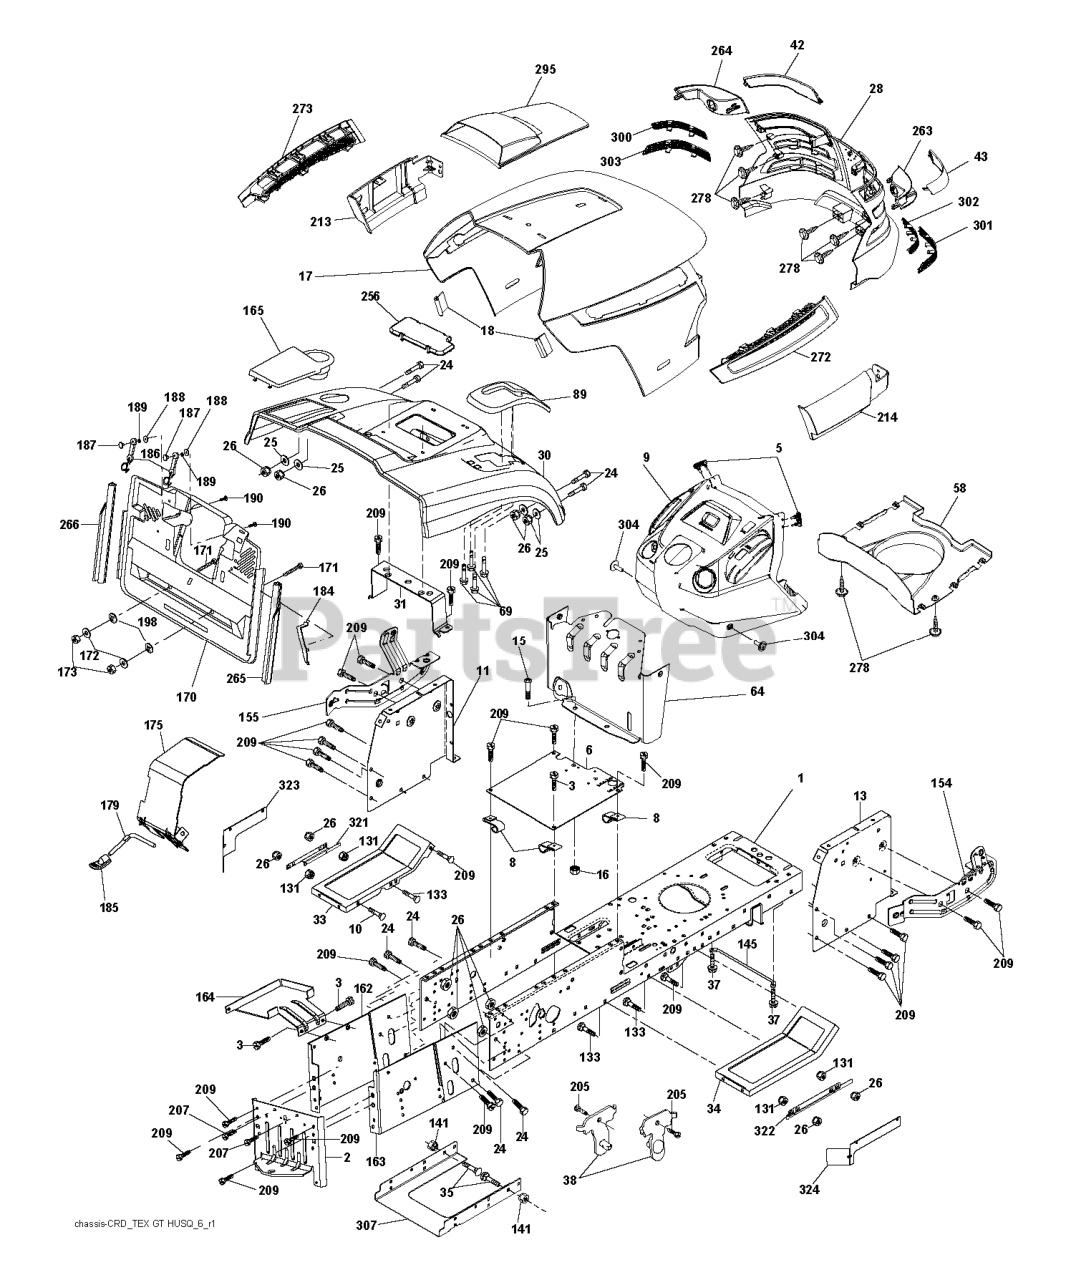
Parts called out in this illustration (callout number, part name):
2	DRAWBAR
3	SCREW 3/8-16X3/4
5	BUMPER DASH
6	PLATE
8	CLIP,INSULATOR
10	BOLT.3/8-14X1.25
11	PANEL DASH LH
13	PANEL DASH RH
15	Screw, Machine, Truss Head 5/16-18 UNC x 3/4
16	NUT
17	HOOD
18	BUMPER.HOOD.TEX.HUSQVARNA
25	WASHER
26	NUT
28	GRILL.ASM.HUSQ.TG/CRD.W/TRIM
30	CONSOLE.CRD.AUTO.GRY
31	BRACKET SUPPORT FENDER
33	FOOTREST PNT LH
34	FOOTREST PNT RH
37	Screw 5/16-18 x 1/2 Hex, Self Tapping 5/16-18 x 1/2
38	BRACKET ASM PIVOT MOWER REAR
42	LENS.LH.TEX.GT.HUSQ.CL
43	LENS.RH.TEX.GT.HUSQ.CL
58	AIR.DUCT.HOOD.TEX.GT.HUSQ
69	SCREW.HI-LO.CONSOLE
89	CONSOLE.CRD.AUTO.GREY.2005
131	NUT.HEX.3/8-16UNC
133	BOLT D
141	NUT LOCK FLG 3/8-16 UNC
145	ROD.PIVOT.HOOD
162	BRACKET
163	BRACKET EXTEN CHASSIS RH CRD
165	COVER.BATTERY.BGGR.ELE
172	WASHER
175	DOOR TRAP
179	ROD PIVOT FBI
184	BRACKET.ACTUATOR.BAGGER.SRD
186	LATCH ASSY
187	WELDNUT
189	LOCKWASHER #10
190	SCREW
207	SCREW, 5/16-18 X 1/2
209	SCREW, 3/8-16X3/4
213	SKIRT.HOOD.SIDE.HUSQ.LH.GREY
214	SKIRT.HOOD.SIDE.HUSQ.RH.GREY
256	COVER FENDER CRD
263	BEZEL.RH.TEX.GT.HUSQ
264	BEZEL.LH.TEX.GT.HUSQ
265	SEALING
266	SEALING
272	VENT.SIDE.HOOD.HUSQ.RH.GREY
273	VENT.SIDE.HOOD.HUSQ.LH.GRAY
278	SCREW.#10 X 0.750.BOS
295	HOOD VENT
300	INSERT.HEX.GRILL.HUSQ.
301	INSERT.HEX.GRILL.HUSQ.GREY
302	INSERT.HEX.GRILL.HUSQ.
303	INSERT.HEX.GRILL.HUSQ.
304	SCREW 14-20 X 5/8
321	SHIELD INNER LEFT
322	SHIELD INNER RIGHT
323	PLATE LEFT
324	PLATE RIGHT
